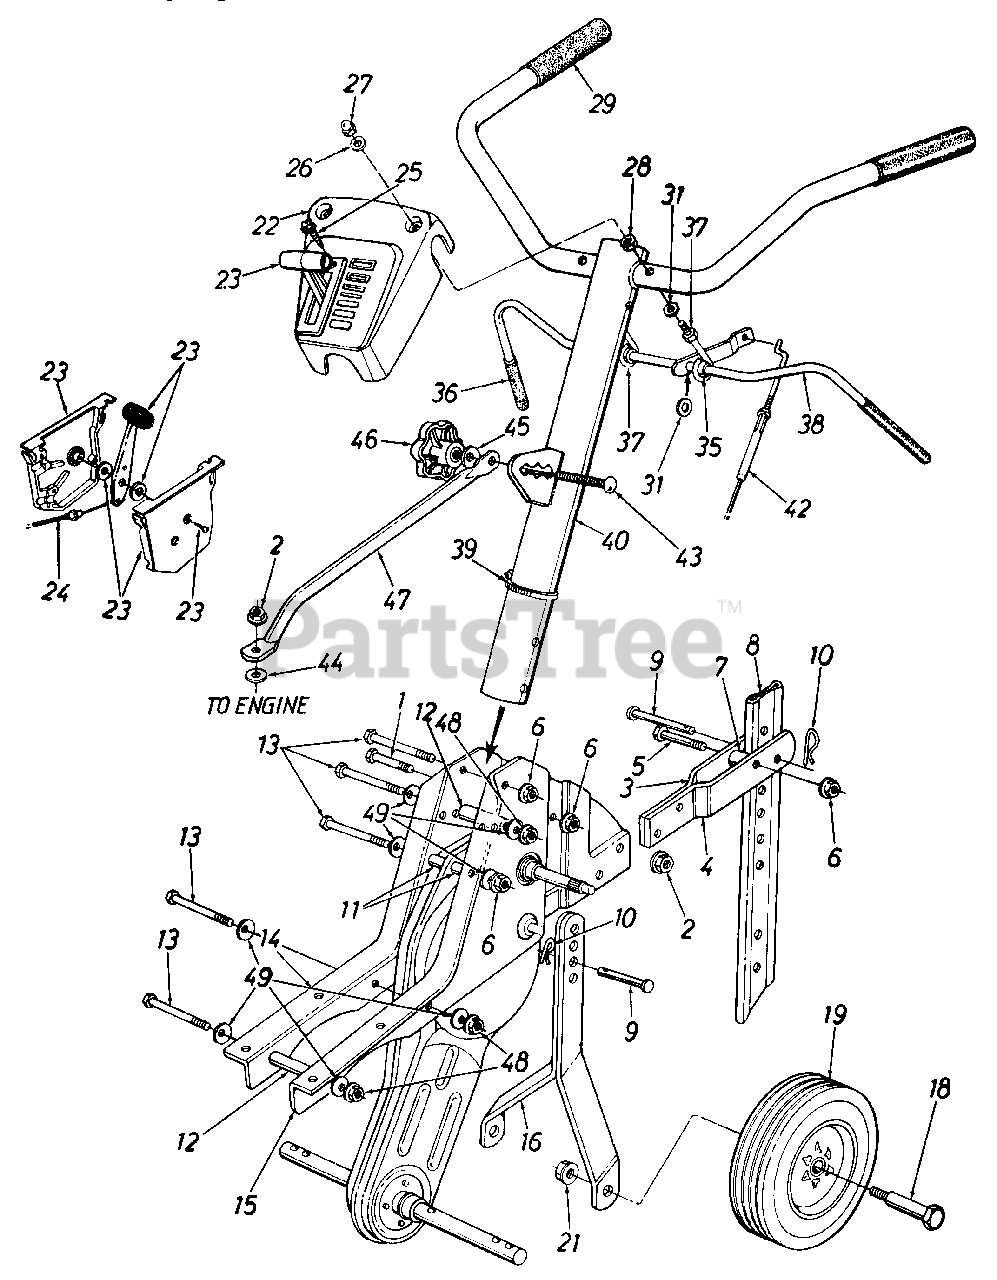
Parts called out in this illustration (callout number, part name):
1	Hex Bolt 5/16-18 x 1.25" Lg.
2	Hex Flange L-Nut 5/16-18 Thd. (Gr. 5)
5	Hex Bolt 5/16-18 x 1.5" Lg.
6	Hex Flange L-Nut 5/16-18 Thd. (Gr. 5)
7	Spacer .32" I.D. x .75" O.D.
9	Clevis Pin .375" I.D. x 1.75" Lg.
10	Internal Cotter Pin
11	Spacer .326" I.D. x .47" O.D.
12	Spacer .322" I.D. x .44" O.D.
13	Hex Bolt 5/16-18 x 2.75" Lg.
19	Wheel Ass'y. 8" x 1.75"
21	Hex Flange L-Nut 3/8-16 Thd. (Gr. 5)
22	Handle Cover
23	Throttle Control Box Ass'y.
24	Throttle Control Wire 30.5" Lg.
25	Truss Mach. AB-Tap Scr. #10 x .5" Lg.
26	Fl-Wash. .266" I.D. x .625" O.D.
27	Hex L-Stop Nut 1/4-28 Thd.
28	Hex Nut 1/4-28 Thd.
29	Grip-Handle
31	Fl-Wash. .385" I.D. x .62" O.D.
35	Plastic Bushing .38" I.D.
36	Grip-Clutch
37	Clutch Handle Eye Bolt
43	Carr. Bolt 5/16-18 x 1" Lg. (Special)
44	Fl-Wash. .344" I.D. x 1.12" O.D.
45	Bell-Wash. .345" I.D. x .88" O.D.
46	Hand Knob
49	Bell-Wash. .345" I.D. x .88" O.D.
